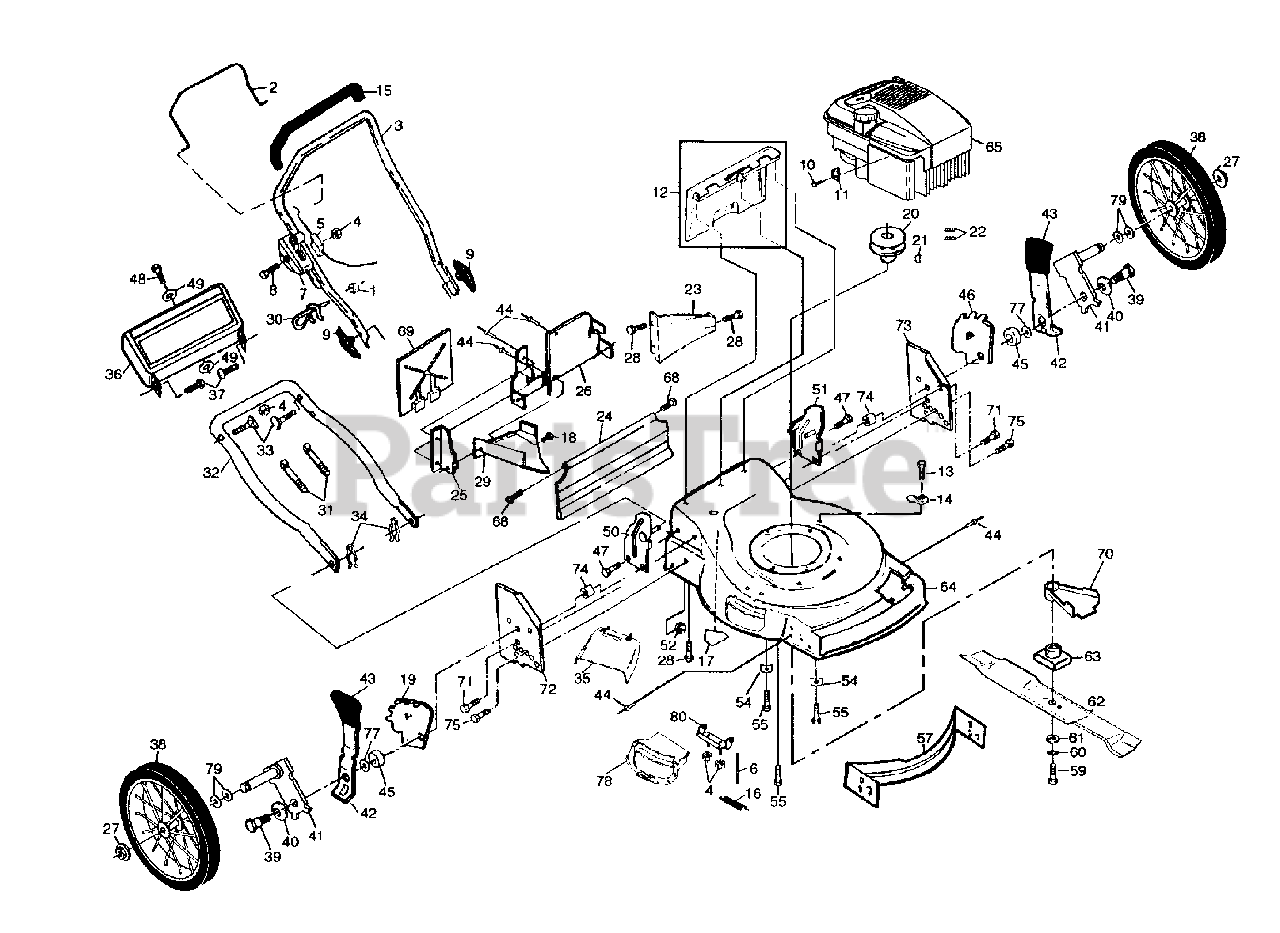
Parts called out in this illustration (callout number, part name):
1	Hex Nut
2	Control Bar
3	Upper Handle
4	Locknut
5	Engine Zone Control Cable
7	Throttle Control
8	Hex Washer Head Screw 1/4-20 x 2-1/8
9	Handle Knob
10	Screw #10 x 5/8
11	Cable Clamp (Engine)
12	Rear Door Kit
13	Hex Washer Head Screw #10-24 x 1/2
14	Housing Cable Guide
15	Handle Grip
16	Hinge Spring
17	Danger Decal
19	Wheel Adjusting Bracket
20	Engine Pulley
21	Hi Pro Key #505
22	Set Screw 1/4-20 x 5/16
23	Rear Baffle
24	Rear Skirt
25	Side Baffle
26	Back Plate
27	Flanged Locknut
28	Screw Hex Head 1/4-20 x 1/2
29	Discharge Baffle
30	Rope Guide
31	Wire Tie
32	Lower Handle
33	Handle Bolt
34	Hairpin Cotter
35	Clip-on Discharge Deflector
36	Trim Plate Assembly
37	Self-tapping Screw #10-24 x .625
38	Wheel & Tire Assembly
39	Shoulder Bolt
40	Spring Washer
41	Axle Arm
42	Selector Spring
43	Selector Knob
45	Spacer
46	Wheel Adjusting Bracket
47	Self-tapping Screw 5/16-18 x 3/4
48	Screw 1/4-20 x 1
49	Flat Washer 1/4-20 x 1.50
50	Handle Bracket (Right)
51	Handle Bracket (Left)
52	Locknut 3/8-16
54	Engine Washer
55	Hex Head Thread Rolling Screw 3/8-16 x 1-1/8
57	Front Baffle
59	Hex Head Machine Screw 3/8-24 x 1-3/8 Gr. 8
60	Helical Lock Washer
61	Hardened Washer
63	Blade Adapter
64	Lawn Mower Housing Kit
65	Engine
68	Hinge Screw
69	Mulcher Plate
70	Debris Shield
71	Thread Cutting Screw 5/16 - 18 x 1-1/5
72	Support Bracket (RH)
73	Support Bracket (LH)
77	Flat Washer
78	Combi-cut Door
79	Wave Washer
80	Hinge Bracket
